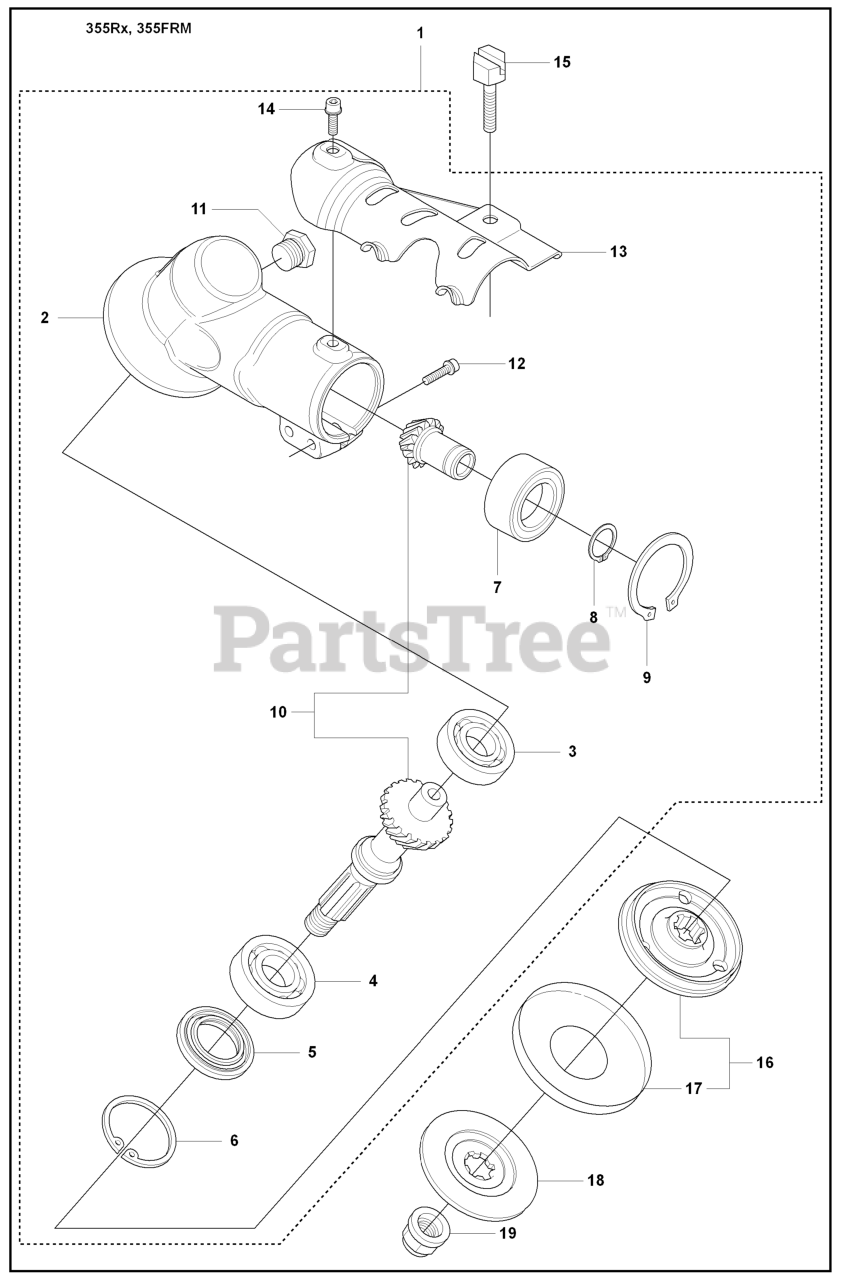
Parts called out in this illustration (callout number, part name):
1	BEVEL GEAR
2	GEAR HOUSING
3	BALL BEARING
4	BALL BEARING
6	RETAINING RING SGH 35
8	RETAINING RING SGA 15
9	RETAINING RING
10	BEVEL GEAR
13	ATTACHMENT PLATE
16	RP CARRIER
17	GRASS SEALING
18	SUPPORT FLANGE
19	BLADE NUT
